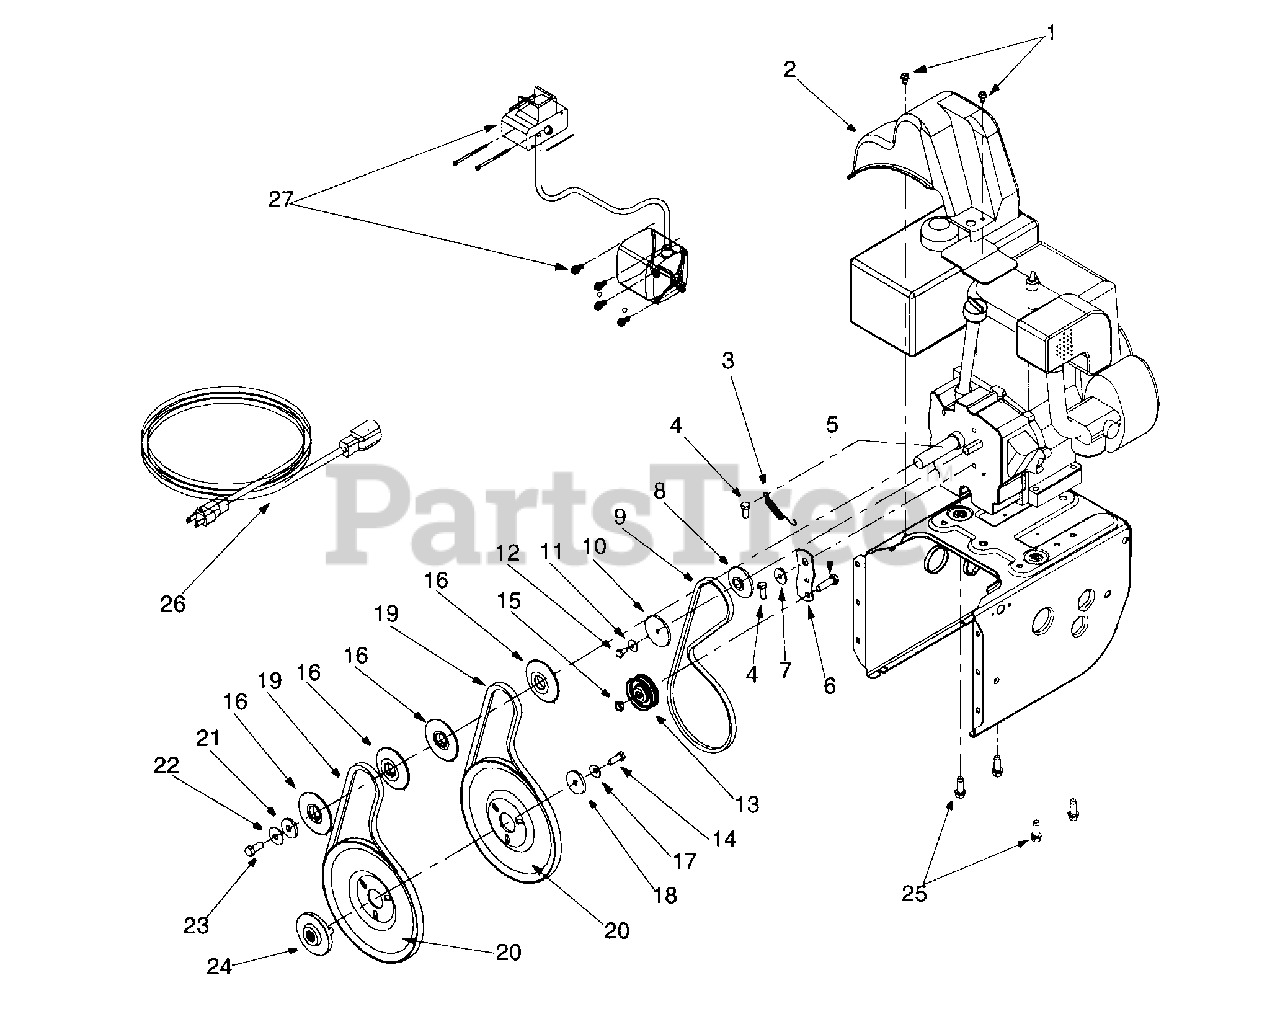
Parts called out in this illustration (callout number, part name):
1	Hex Washer Screw 1/4-20 x .625
2	Belt Cover
3	Extension Spring
4	Hex Screw 5/16-24 x .75
5	Hex Cap Screw 3/8-16 x 1.25
8	Pulley Half
9	V-Belt
10	Pulley Half
11	Bell Washer
12	Hex Cap Screw 1/4-28 x .50
13	Flat Idler
14	Lock Hex Cap Screw 5/16-24
15	Lock Jam Nut 3/8-16
16	Pulley Half
17	Bell Washer
18	Flat Washer
19	Belt
20	Auger Pulley
21	Flat Washer 3/8 x 1.25 OD
22	Bell Washer
23	Hex Cap Screw 3/8-24
24	Adapter Pulley
25	Hex Screw 3/8-16 x 1.0
26	Extension Cord
27	Electric Start
